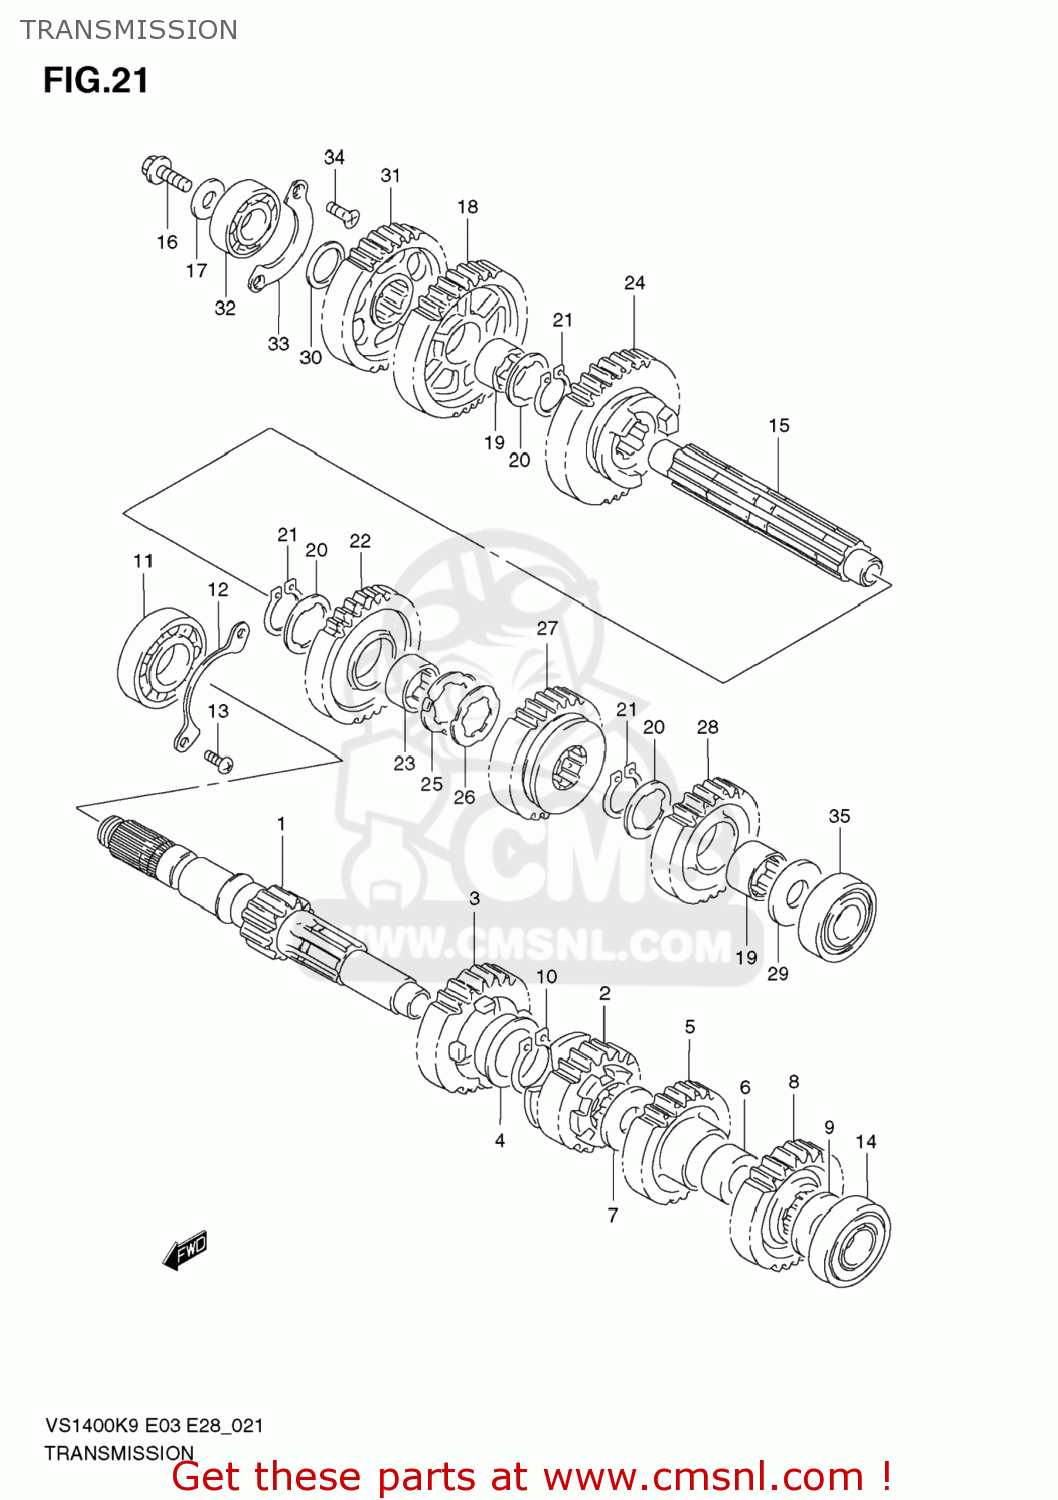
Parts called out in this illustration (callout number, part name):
1	SHAFT,COUNTER
2	GEAR,2ND DRIVE(NT:17)
3	GEAR,3RD DRIVE(NT:21)
4	BUSH(28X32X2)
5	GEAR,4TH DRIVE
6	BUSH,4TH DRIVE GEAR
7	SHIM(22X32X1)
8	GEAR,5TH DRIVE
9	SHIM(20X32X1)
10	CIRCLIP
11	BEARING(25X62X17)
12	RETAINER,CNTR SHAFT BEARING
13	BOLT(6X12)
14	BEARING(20X52X15)
15	SHAFT,DRIVE
16	BOLT(10X24)
17	WASHER
18	GEAR,1ST DRIVEN(NT:36)
19	BUSH
20	WASHER,LOCK
21	CIRCLIP
22	GEAR,2ND DRIVEN(NT:31)
23	BUSH,3RD DRIVEN GEAR
24	GEAR,3RD DRIVEN(NT:28)
25	WASHER
26	WASHER,LOCK
27	GEAR,4TH DRIVEN(NT:25)
28	GEAR,5TH DRIVEN
29	WASHER
30	WASHER(22X32X3)
31	GEAR,OVER DRIVING DRIVE(NT:34)
32	BEARING(22X56X16)
33	RETAINER,CNTR SHAFT BEARING
34	SCREW(6X12)
35	BEARING(20X52X15)
